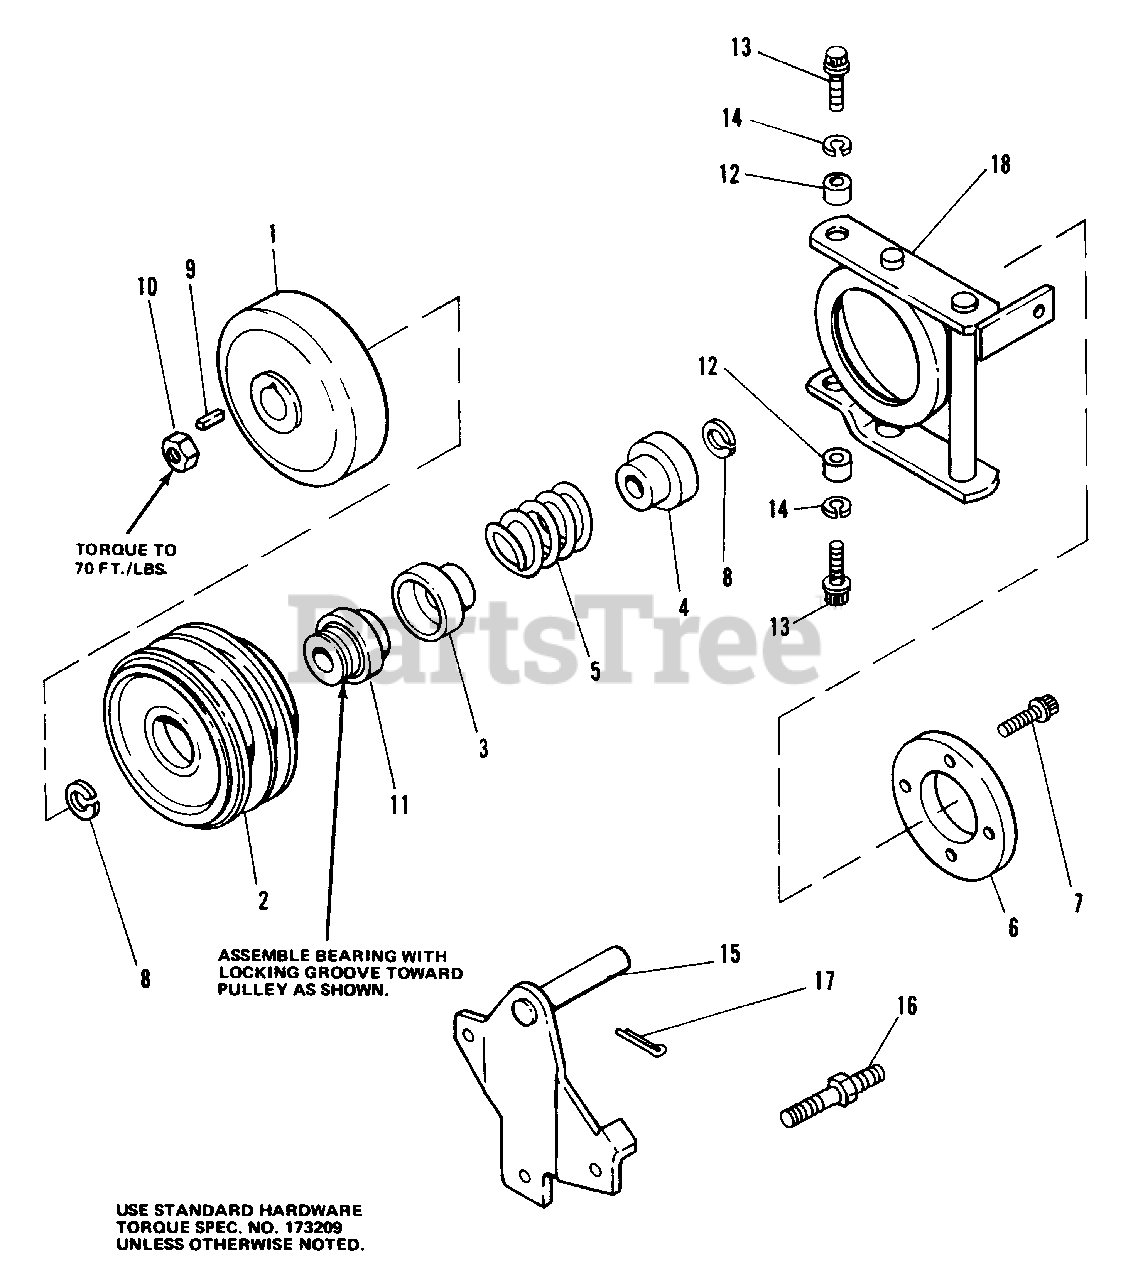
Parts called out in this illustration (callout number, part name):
1	CLUTCH PLATE ASSEMBLY
3	GUIDE, Spring
4	GUIDE, Spring
6	DISC, Brake
7	CAPSCREW, Skt. Hd., 1/4-20 x 5/8
8	RING, Retaining
10	NUT, Hex, Lock, 3/4-16
11	BEARING ASSEMBLY
13	SCREW,Thd. Forming
14	LOCKWASHER, 5/16
15	PIVOT ARM ASSEMBLY
17	PIN, Cotter, 3/16 x 1-1/2
18	PIVOT ASSEMBLY
